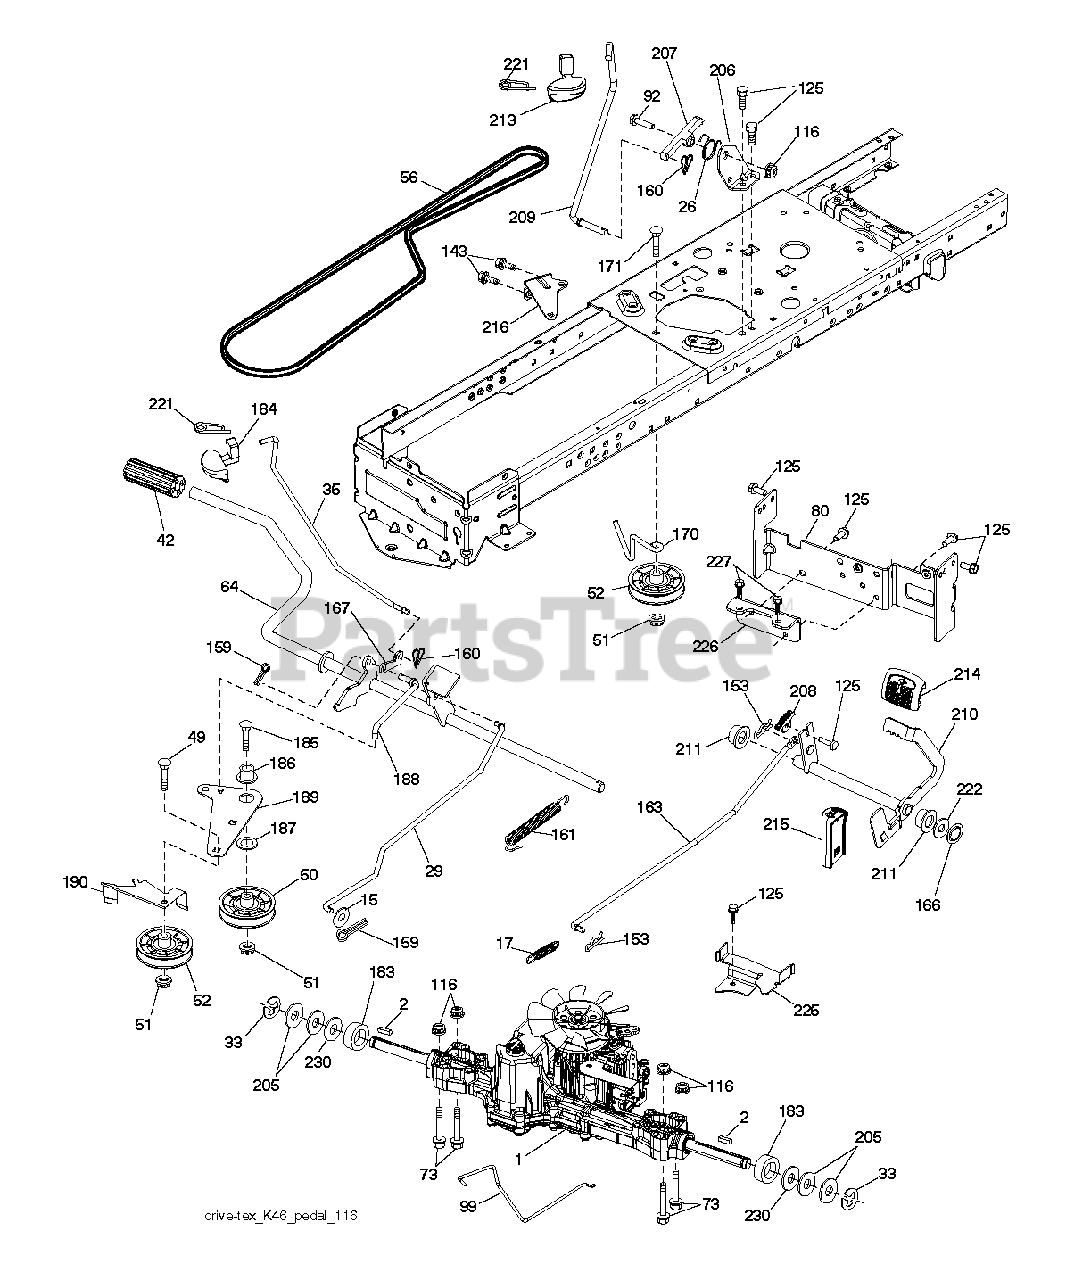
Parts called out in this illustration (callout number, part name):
2	SQUARE KEY
17	SPRING.BRAKE.K46.GREEN
26	SPRING.RETURN.CRUISE
29	ROD.BRAKE.K46
33	E-RING LT
35	ROD.BRAKE.PARKING.LT.T
49	BOLT
50	IDLER.FLAT.910.OFFSET
51	NUT LOCK FLG 3/8-16 UNC
52	IDLER.V-GROOVE.910.OFFSET
56	V-BELT.MOWER.92.40.42/K46
64	SHAFT.ASM.PEDAL.BRK.CNTR
80	STRAP.TORQUE.K46.K57R.TT
92	BOLT
99	ROD.SPRING.BYPASS.K46.LT.Z
116	NUT LOCK HEX FLANGE 5/16-18
125	SCREW
143	SCREW LT
159	COTTER PIN
160	RETAINER CLIP
161	SPRING, RETURN LT
163	ROD.CONTROL.K57R.K46
166	NUT.PUSH.625
167	LATCH.BRAKE.SPRING
170	KEEPER.V-IDLER.CENTER.
171	BOLT
183	SPACER AXLE
184	HANDLE.PARKING.BRAKE.LTTEX.667
186	SPACER.RETAINER
187	WASHER 12/32X2X10GA
188	LINK.CLUTCH.GROUND.DRIVE
189	BELLCRANK.GROUND.DRIVE.TEX.
190	KEEPER.BELLCRANK.DRIVE
206	BRACKET.MOUNT.CRUISE.LATCH
207	LATCH.CONTROL.CRUISE
208	GEAR.SECTOR.CONTROL.CR
210	ROCKER.ASM.PEDAL.CONTR
211	BEARING.NYLON
213	HANDLE.CONTROL.CRUISE.ELTE
214	PEDAL.FORWARD.PAD.TEX
215	PEDAL.REVERSE.TEX.GT.4
216	BRACKET.PULLEY.IDLER.W/TEX
221	RETAINER.SPRING.CLIP.H
222	WASHER 21/32 X 1-1/4 X 10 GA.
225	KEEPER.BELT.TRANSAXLE.K46
226	BRACKET.MOUNT.TORQUE.K46.TLT
227	Screw, Lt
230	WASHER.HARDENED
